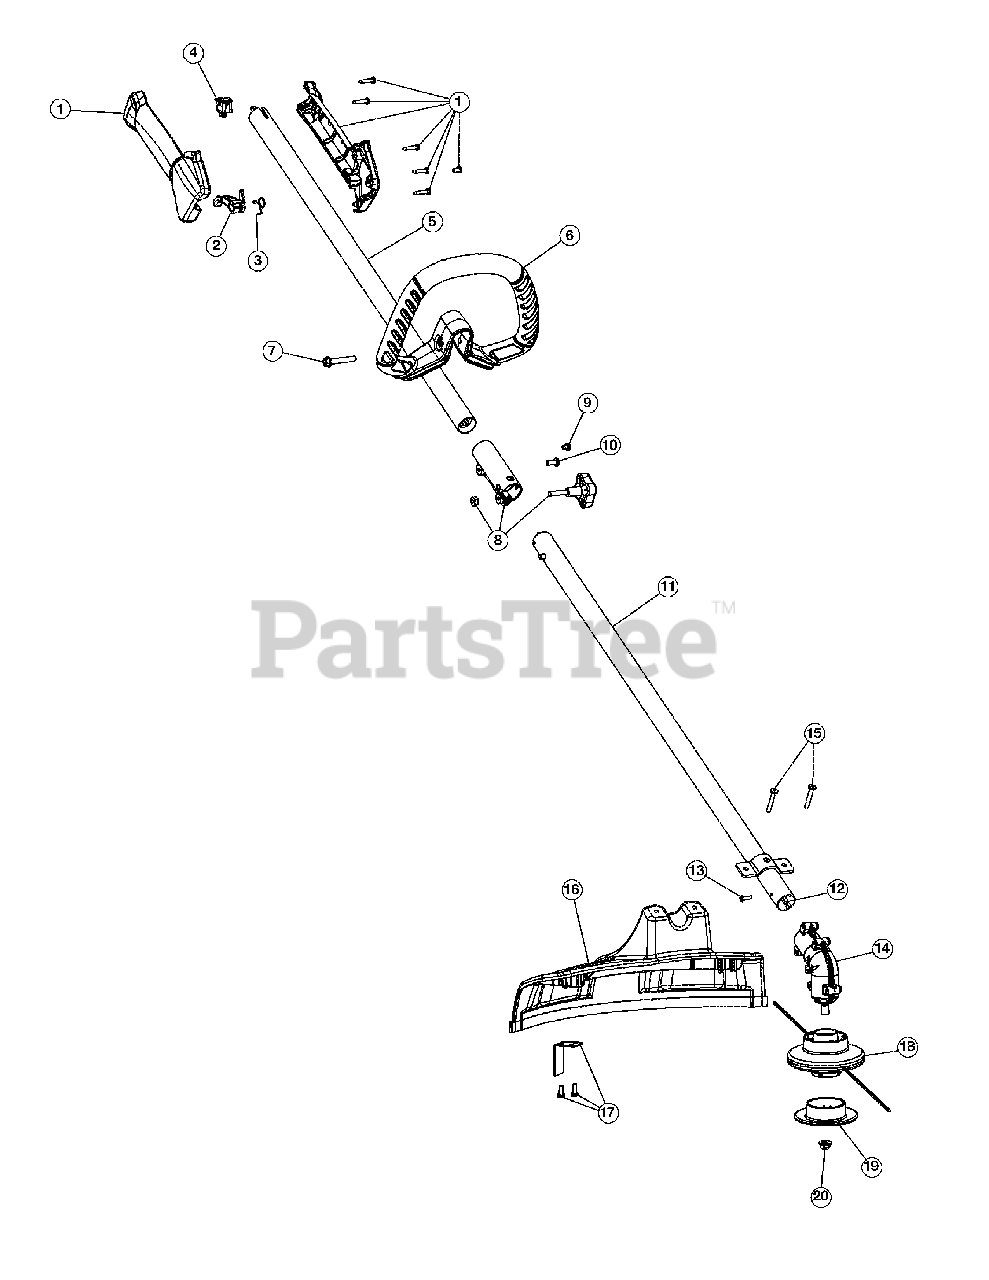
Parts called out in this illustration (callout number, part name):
1	Throttle Housing Assembly (Incl. 2 - 4)
2	Throttle Trigger
3	Throttle Trigger Spring
5	Upper Drive Shaft Housing Assembly
6	D-Handle Assembly (Incl. 8)
8	Split Boom Coupler (Incl. 10 and 11)
8	Knob, Adjustment
8	Nut, Retaining
11	Lower Drive Shaft Housing Assembly
12	Lower Flexible Drive Shaft
13	Anti-Rotation Screw
14	Gear Box Assembly (Incl. 14, 19 - 21)
15	Shield Mounting Screw
16	Shield Assembly (Incl. 18)
17	Blade Assembly
18	Cutting Head Assembly (Incl. 20 and 21)
